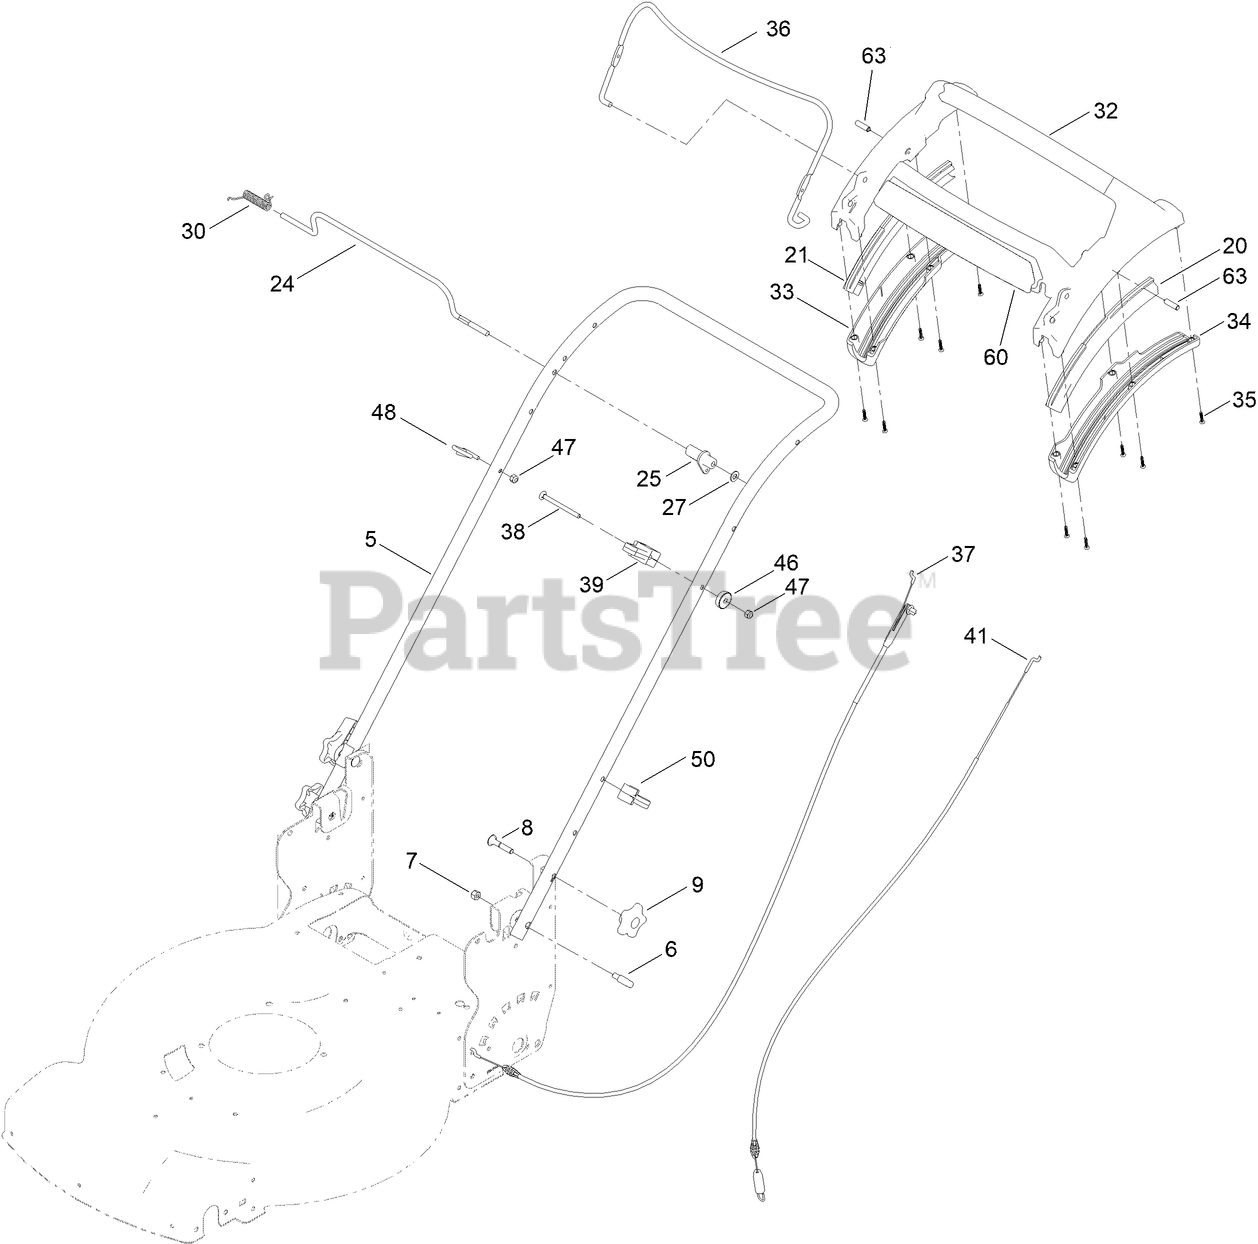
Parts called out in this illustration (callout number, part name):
5	HANDLE-CURVED
6	BOLT-SHOULDER, HANDLE
7	NUT-HEX
8	SCREW-CARR
9	KNOB-HANDLE
20	GUIDE-CURVED, LH (RWD)
21	GUIDE-CURVED, RH (RWD)
24	ROD-CONTROL, TRACTION
25	LEVER-TRACTION, RWD
27	WASHER-PLAIN
30	SPRING-TORSION
32	HANDLE-PERSONAL PACE, CURVED
33	BOTTOM-HANDLE, RH
34	BOTTOM-HANDLE, LH
35	SCREW-PPH
36	BAIL-BRAKE
37	CABLE-BRAKE, PP BS
38	SCREW-CARR
39	ANCHOR-CABLE, RWD
41	CABLE-TRACTION, RWD (PP)
46	WASHER-CURVED
47	NUT-HEX
48	GUIDE-ROPE
50	GUIDE-CABLE
60	DECAL - ADS, HANDLE
63	PIN-HANDLE, PP
